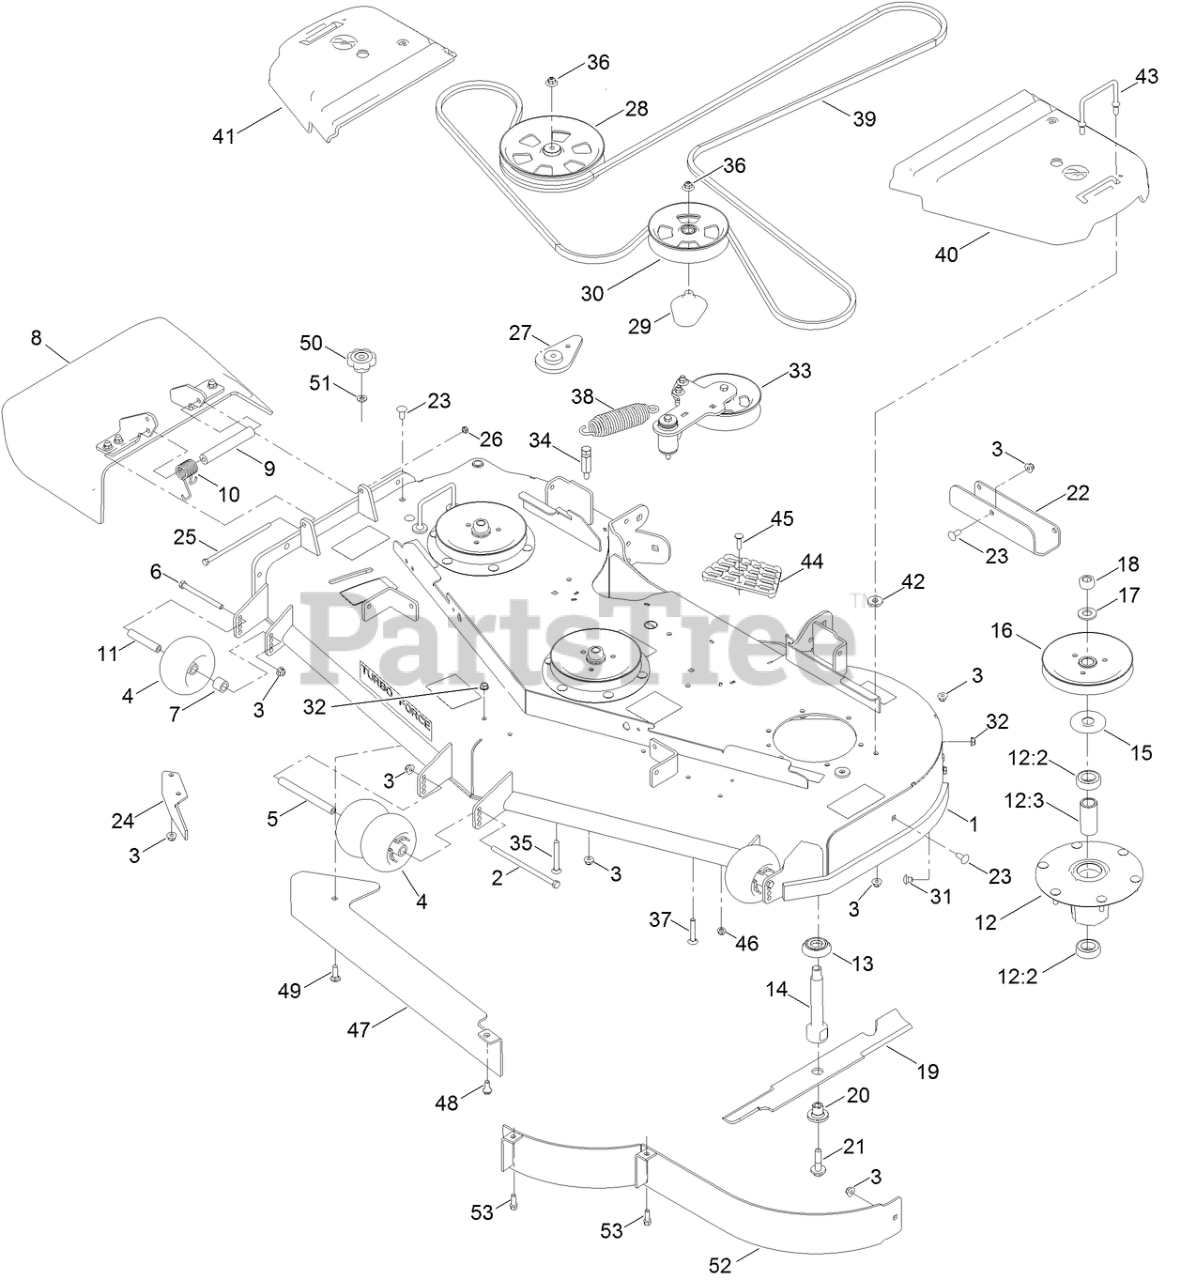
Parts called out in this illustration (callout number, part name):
1	DECK DECAL ASM
2	SCREW-HH
3	NUT-HF, NI
4	ROLLER-SCALP, ANTI
5	SPACER-WHEEL
6	SCREW-HH
7	TUBE-SPACER
8	RUBBER DEFLECTOR ASM
9	SPACER
10	SPRING-TORSION
11	TUBE-SPANNER
12	SPINDLE ASM
12:2	BEARING-BALL
12:3	SPACER-BEARING
13	GUARD-BOTTOM
14	SHAFT-SPINDLE
15	GUARD-BEARING, TOP
16	SHEAVE-DRIVE, BLADE
17	WASHER
18	NUT-HEX
20	BUSHING-HEX
21	SCREW-SEMS
22	PLATE-SKID
23	SCREW-CARR
24	BAFFLE-DISCHARGE
25	SCREW-HH
26	NUT-LOCK, NI
27	SPACER-IDLER
28	PULLEY-IDLER,FLAT
29	SPACER-PULLEY
30	PULLEY-IDLER, FLAT
31	SCREW-CARR
32	NUT-HHF, WHIZ
33	IDLER ARM ASM
34	ANCHOR-SPRING, TALL
35	SCREW-CARR
36	NUT-FLANGE, NI
37	BOLT-CARR, SHORT NECK
38	SPRING-EXTENSION
39	BELT-V
40	COVER-BELT, LH
41	COVER-BELT, RH
42	WASHER
43	WIREFORM-COVER
44	STEP-DECK
45	SCREW-CARR
46	NUT-HF, NI
47	PLATE-BAFFLE
48	BOLT-SHOULDER
49	BOLT-CARR
51	WASHER-HARDENED
